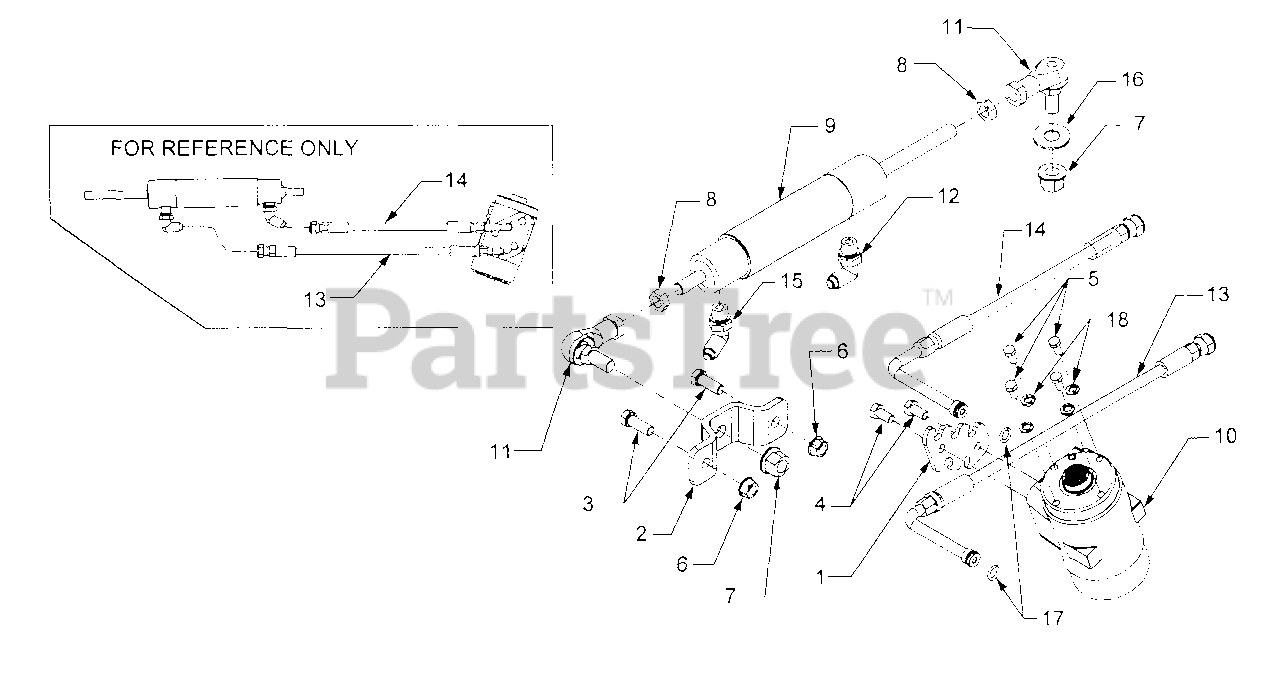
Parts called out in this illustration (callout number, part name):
1	Plate, Steering Pump Port
2	Bracket, Cylinder Mounting
3	Screw, Hex Cap 3/8-16 x 1.0 GR5
4	Screw, Hex Cap M8-1.25 x 16MM GR5
5	Screw, Hex Cap, M6 x 14MM
6	Nut, Hex Flange Lock, 3/8-16
7	Nut, Hex Flange Lock, M12 x 1.75
8	Nut, Hex, M12 x 1.75 RH
9	Cylinder, Steering
10	Pump, Hydraulic Steering
11	Ball Joint, 12MM x 1.75 RH
12	Fitting, 90 Degree Elbow
13	Hose, Front Steering
14	Hose, Rear Steering
15	Fitting, 45 Degree
16	Washer, Flat, .51 x 1.12 x .060
17	O-Ring, .426 x .566 x .070
18	Washer, Lock, 1/4"
